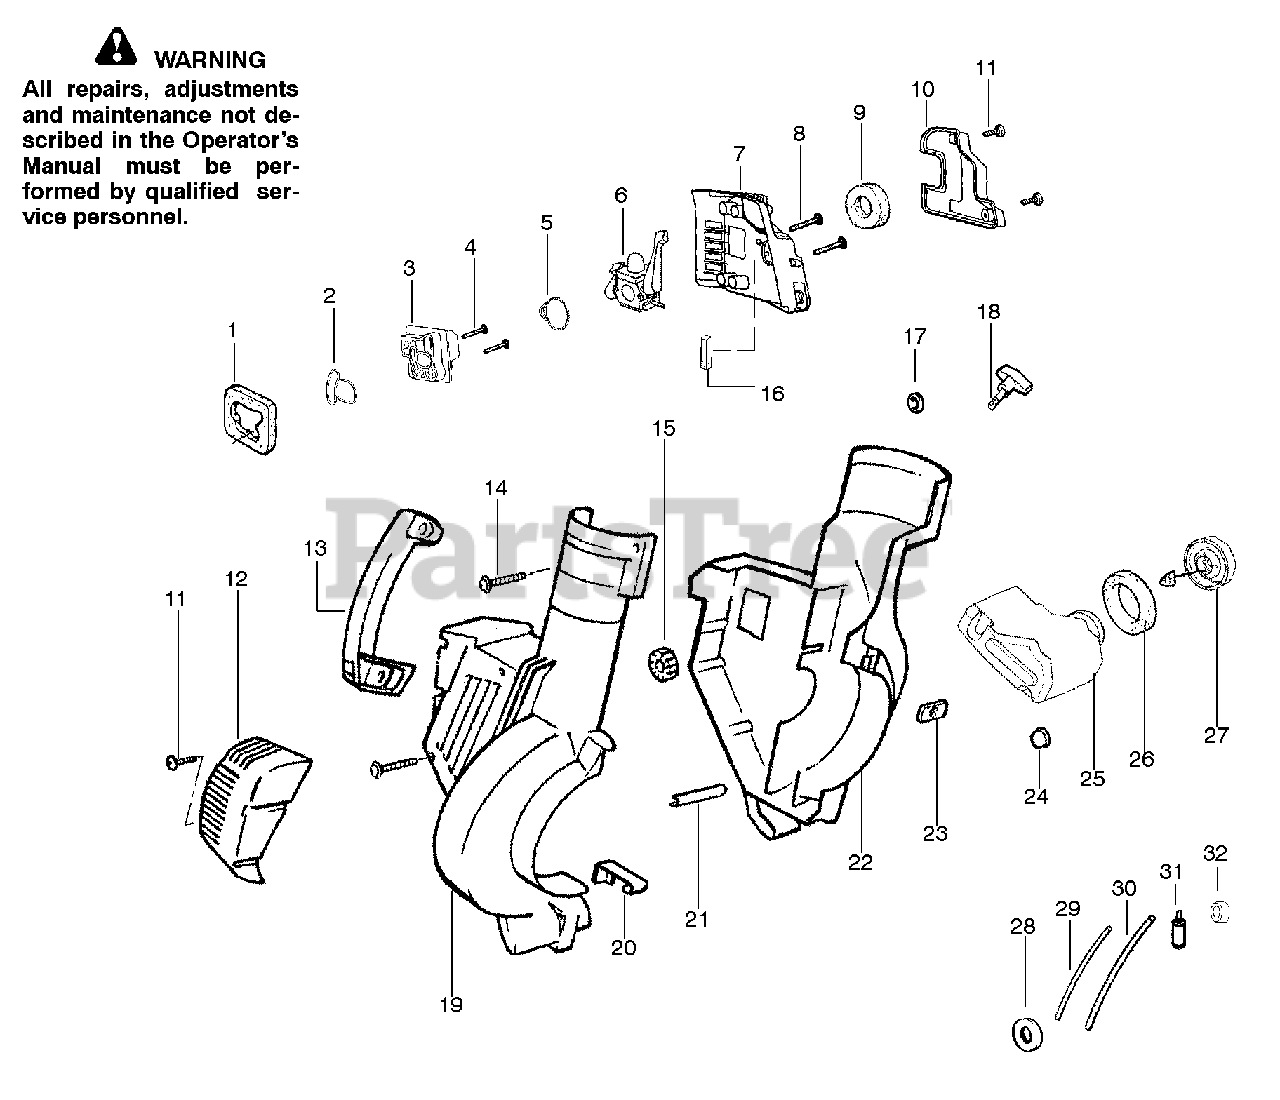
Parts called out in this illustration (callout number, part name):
1	Air Dam (kit)
2	Gasket-Adapter (kit)
3	Carburetor Adaptor
5	Gasket-Carburetor (kit)
6	Kit-Carb Ass'y. (C1Q-W11)
6	Kit-Carb Ass'y. (C1Q-W11C)
6	Kit-Carb Ass'y. (WT-606)
8	Screw-Carb.
9	Filter-Air
10	Cover-Air Filter
12	Guard-Muffler
15	Isolator
16	Foam 25.4mm (kit)
18	Knob-Tube Clamp
19	Housing-Right
20	Spring-Cover Latch
21	Guide-Starter Rope
22	Housing-Left
24	Isolator-Crankcase
25	Assy-Fuel Tank
26	Gasket-Fuel Tank
27	Fuel Cap w/Retainer
28	Grommet-Shroud
29	Kit-Line Carb/Purge
30	Kit-Line Tank/Purge
31	Assy-Fuel Pick-up
32	Grommet-Fuel line (kit)
